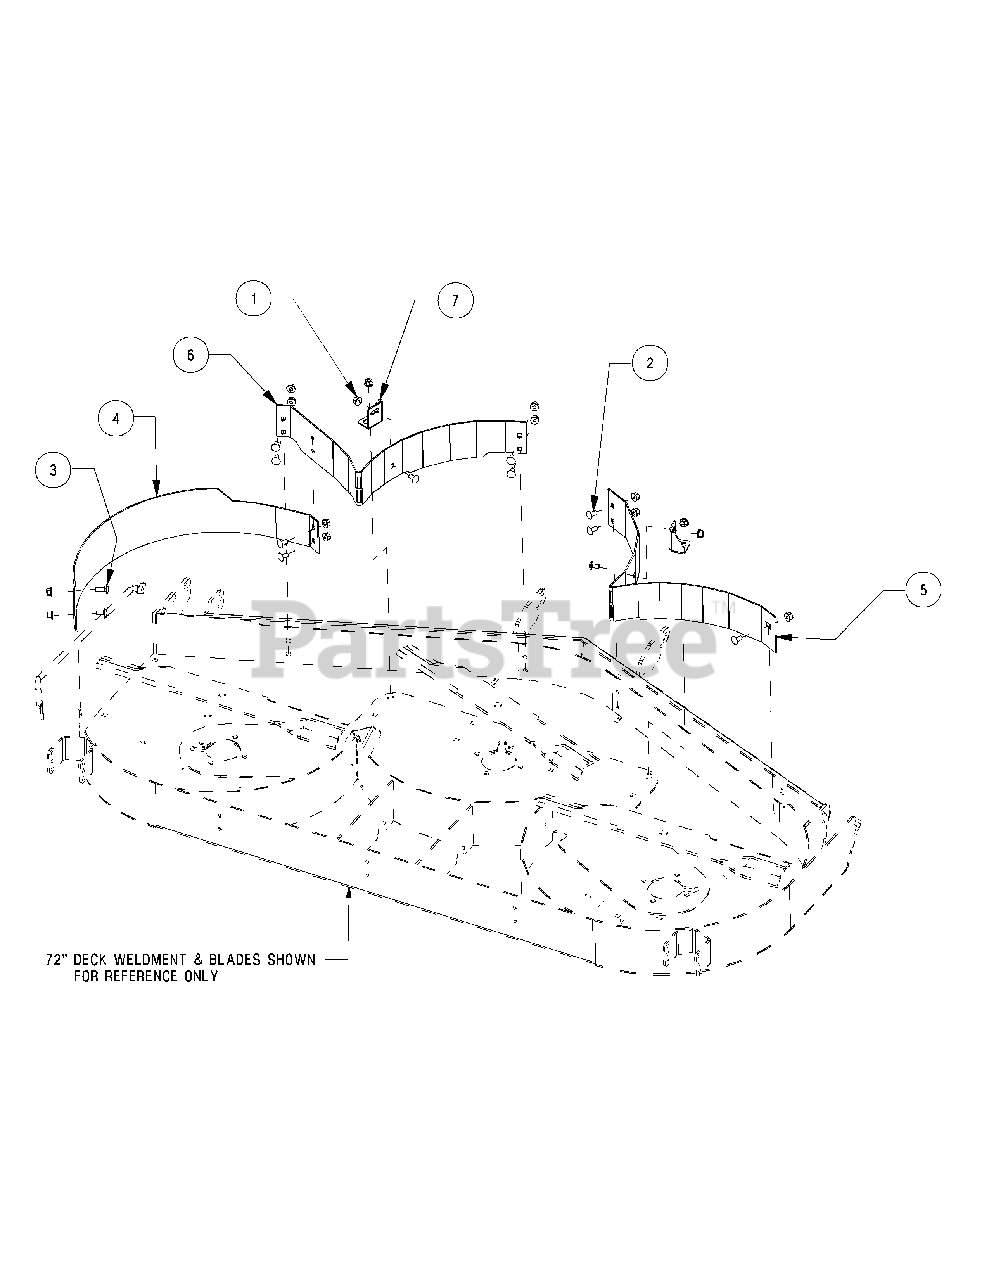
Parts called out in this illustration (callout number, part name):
1	Hex Nut, 3/8-16 Flange Lock
2	Carriage Bolt, 3/8-16 x .75 Long
3	Carriage Bolt, 3/8-16 x 1.00 Long
4	Baffle:Mulch:Fab 72 RH
5	Baffle:Mulch: Fab 72 LH
6	Baffle:Mulch:Fab 72 Center
7	Support Bracket
